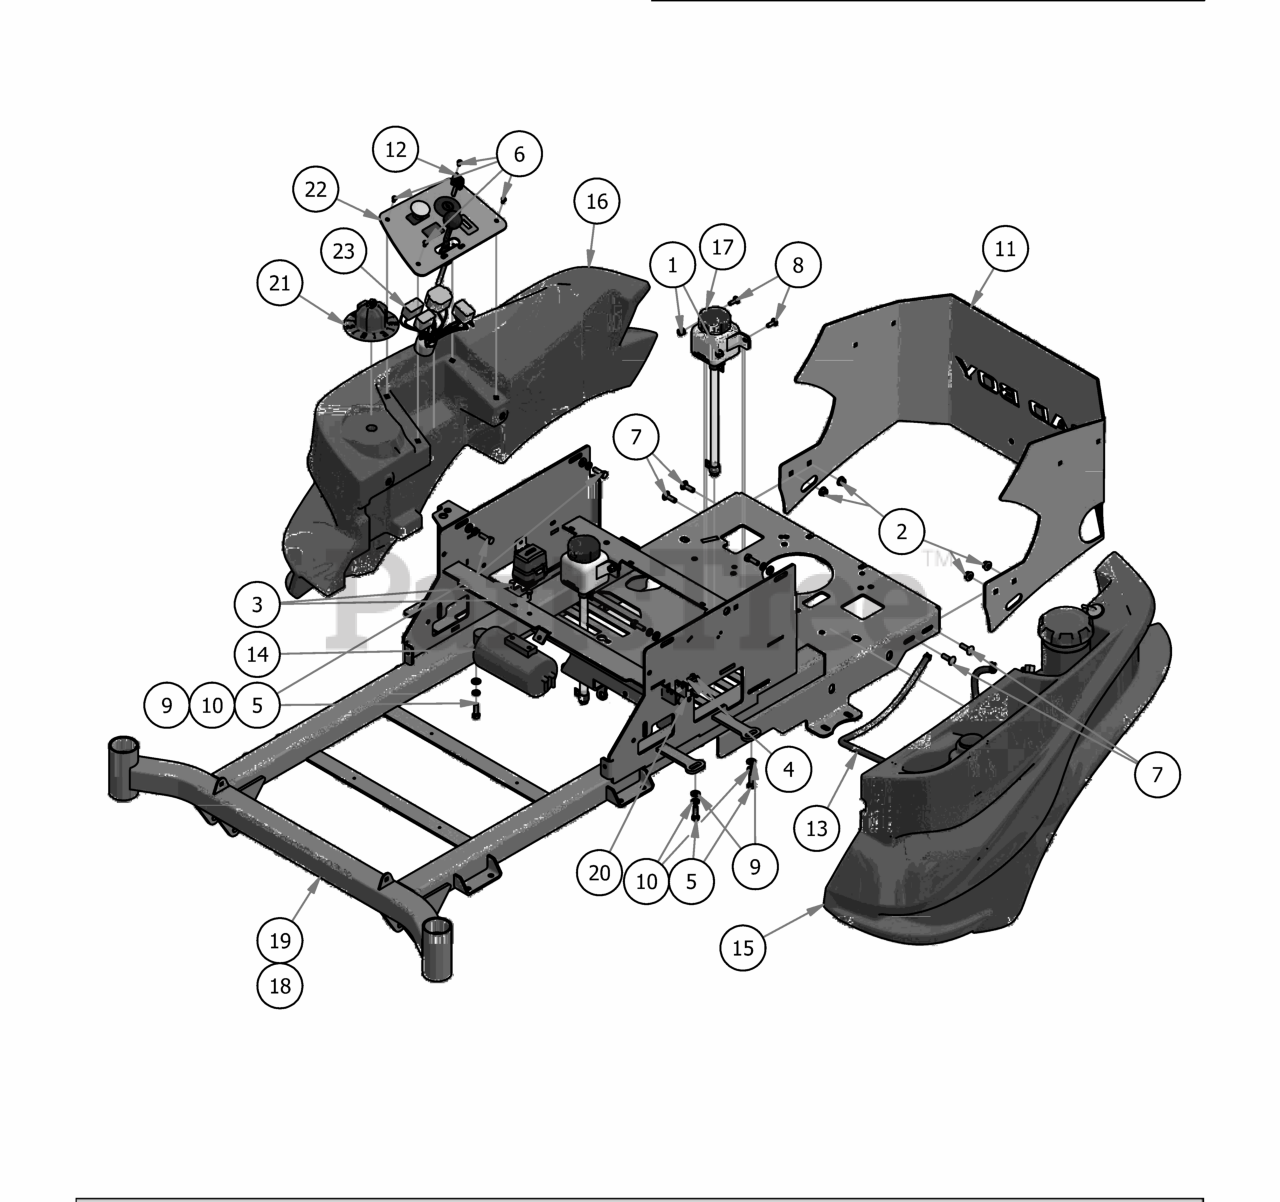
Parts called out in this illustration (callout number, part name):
1	1/4-20 Nylon Insert flange Nut
2	5/16" Nylock Flange Nut Zinc
3	M6-1.0 X 16MM Hex Bolt
4	12-24x 1/2 HWH Bolt
5	5/16" x 1" Bolt
6	10-32 x 3/8" Button Socket Head Bolt
7	5/16" x 1" Carriage Bolt
8	1/4" x 3/4" Carriage Bolt
9	5/16" Flat Washer
10	5/16" Lock Washer
11	2017 ZT Rear Plate
12	Ignition Key
13	37" Fuel Line Assembly
14	ZT/Mav EPA Cannister Assy
15	Left Fuel Tank
16	Right Side Console
17	Hydro Tank Assembly
18	ZT 54" and 60" Frame
19	ZT 48" Frame
20	Safety Switch
21	MZ/ZT Deck Height Dial
22	2019 Control Panel Assembly
23	Wiring Harness
